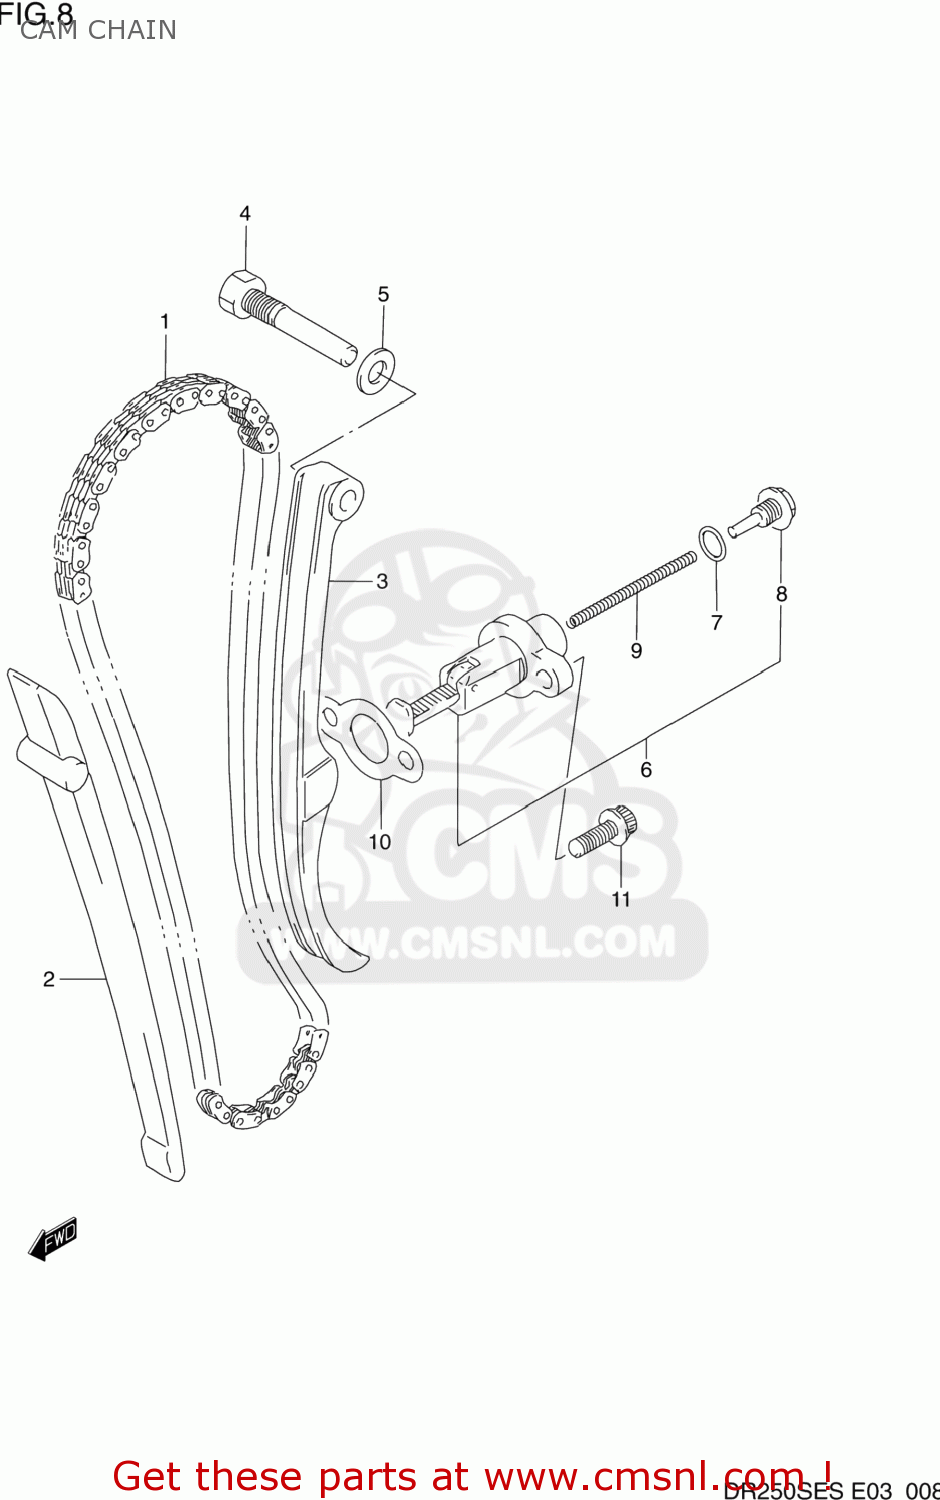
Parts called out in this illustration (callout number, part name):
1	CHAIN,CAMSHAFT DRIVE
2	GUIDE,CAM CHAIN
3	TENSIONER,CAM CHAIN
4	BOLT,CAM CHAIN TENSIONER
5	GASKET 8.2X14X1 (NAS)
6	ADJUSTER ASSY,TENSIONER
7	O RING
8	PLUG,ADJUSTER
9	SPRING
10	GASKET,TENSIONER ADJUSTER (NAS)
11	BOLT
